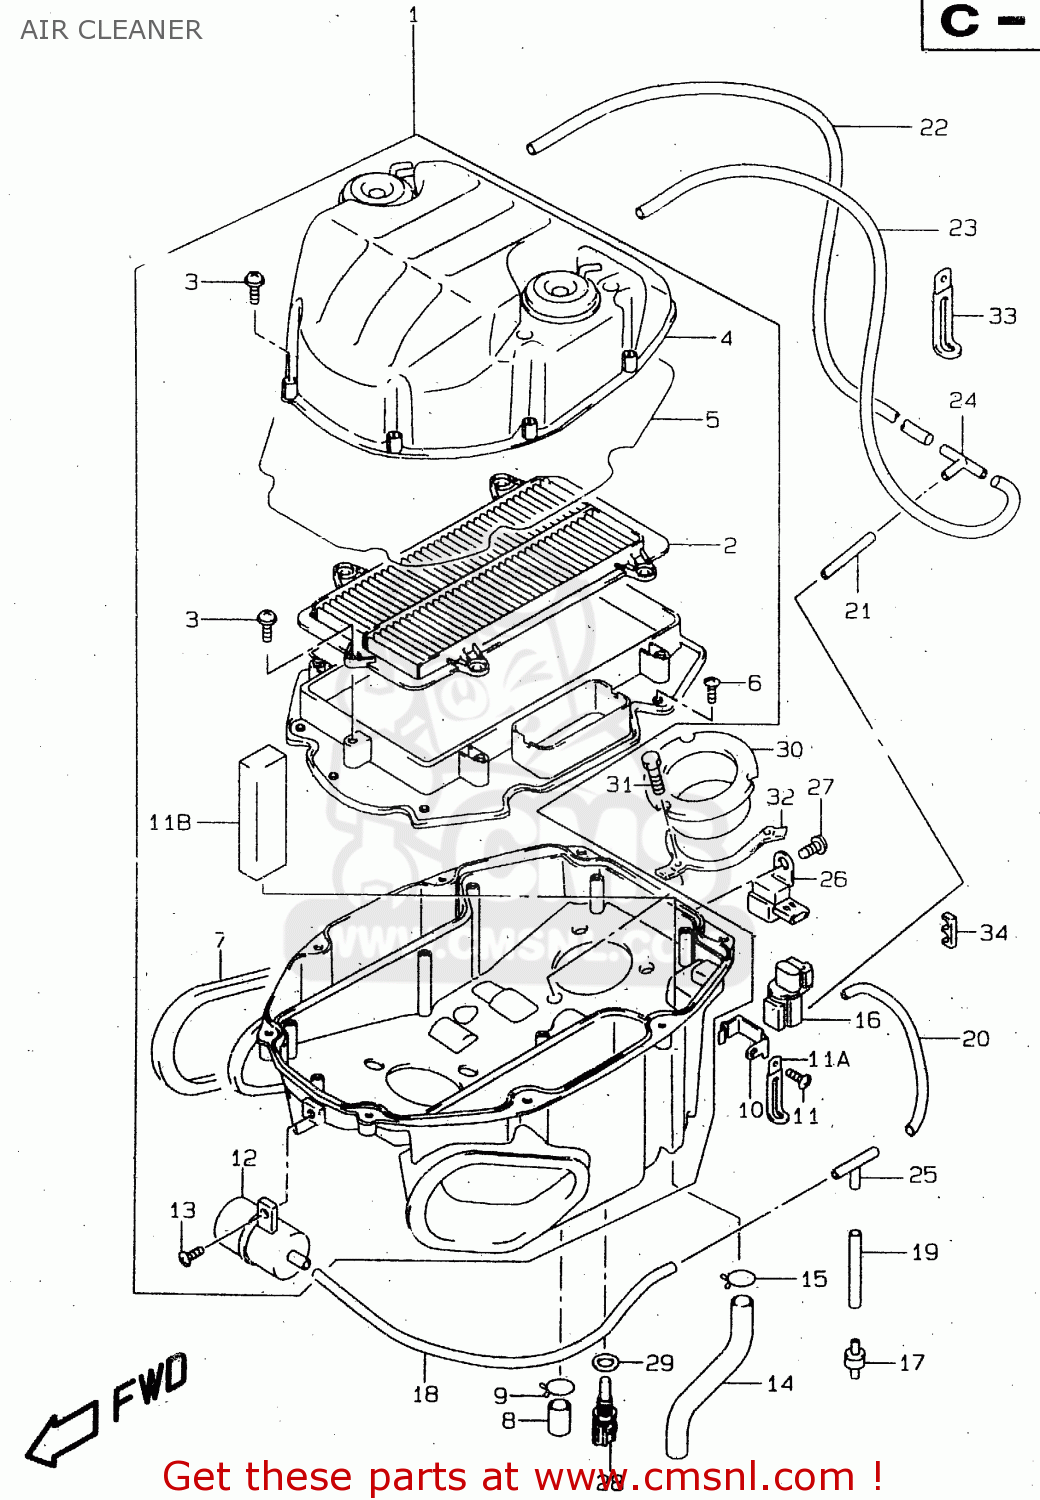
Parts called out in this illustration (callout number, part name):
1	CLEANER ASSY,AIR
2	FILTER,AIR CLEANER
3	SCREW,AIR CLEANER
4	CAP,AIR CLEANER
5	GASKET (NAS)
6	SCREW
7	CUSHION,DUCT
8	PLUG
9	CLIP
10	BRACKET,SOLENOID VALVE
11	SCREW 6X12
11A	CLAMP(L:65)
11B	FILTER,BREATHER
12	CHAMBER,VACUUM
13	SCREW
14	TUBE,BREATHER
15	CLIP
16	VALVE ASSY,3WAY SOLENOID
17	VALVE,CHECK
18	HOSE(3.5X7.5X600)
19	HOSE(3.5X7.5X600)
20	HOSE(3.5X7.5X600)
21	HOSE(3.5X7.5X600)
22	HOSE(3.5X7.5X600)
23	HOSE(3.5X7.5X600)
24	3WAY,VACUUM HOSE
25	3WAY,VACUUM HOSE
26	SENSOR,BOOST
27	SCREW 6X12
28	SENSOR,WATER TEMP
29	GASKET(12.2X21X0.8) (NAS)
30	FUNNEL,AIR CLEANER
31	BOLT(6X20)
32	WASHER,AIR FUNNEL
33	CLAMP(L:65)
34	CLAMP
